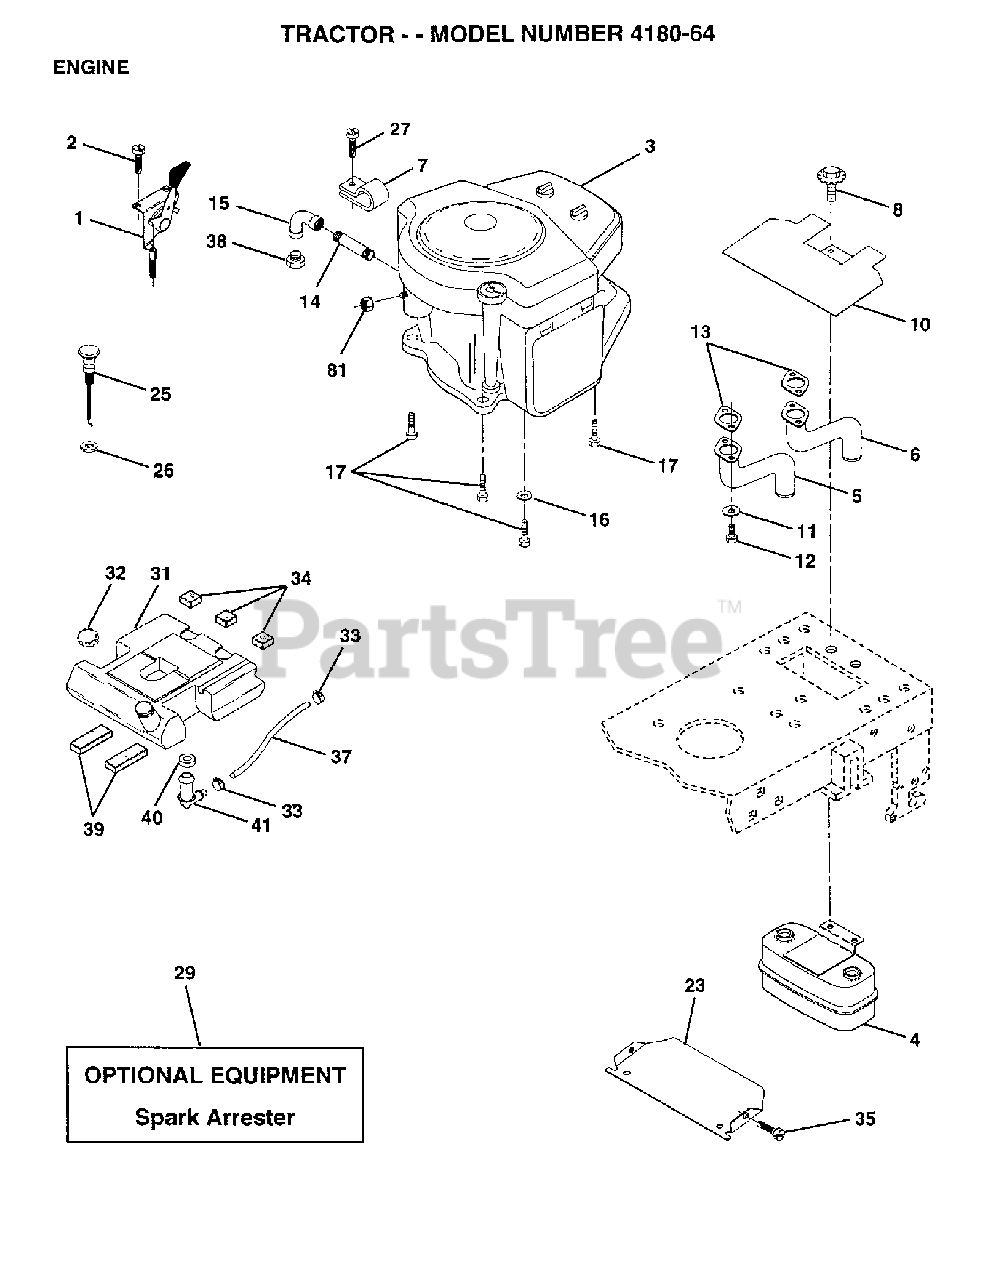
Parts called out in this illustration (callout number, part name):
1	DECK W/DECALS 72" HUS
4	MUFFLER.TWIN.CYL.LOW.TONE
5	EXHAUST ASM. LEFT
6	EXHAUST ASM. RIGHT
10	SHIELD HEAT LT
11	LOCKWASHER
13	GASKET (B&S 692282)
14	NIPPLE, PIPE 3/8NPT X 4-1/2
15	ELBOW
16	LOCKWASHER
25	CONTROL.CHOKE.51.00.BLK.W/BEND
26	NUT KEPS 3/8 - 24 UNF
27	SCREW.TT.#10-32X.5.3/8.FLANGE
29	KIT.SPARK ARRESTOR(392390 B&S)
31	FUEL TANK
33	HOSE CLAMP
34	PAD-SPACER LT
35	Screw, Lt
37	FUEL LINE
39	PAD IDLER TI
40	BUSHING OUTLET T
41	STEM FUEL TANK
